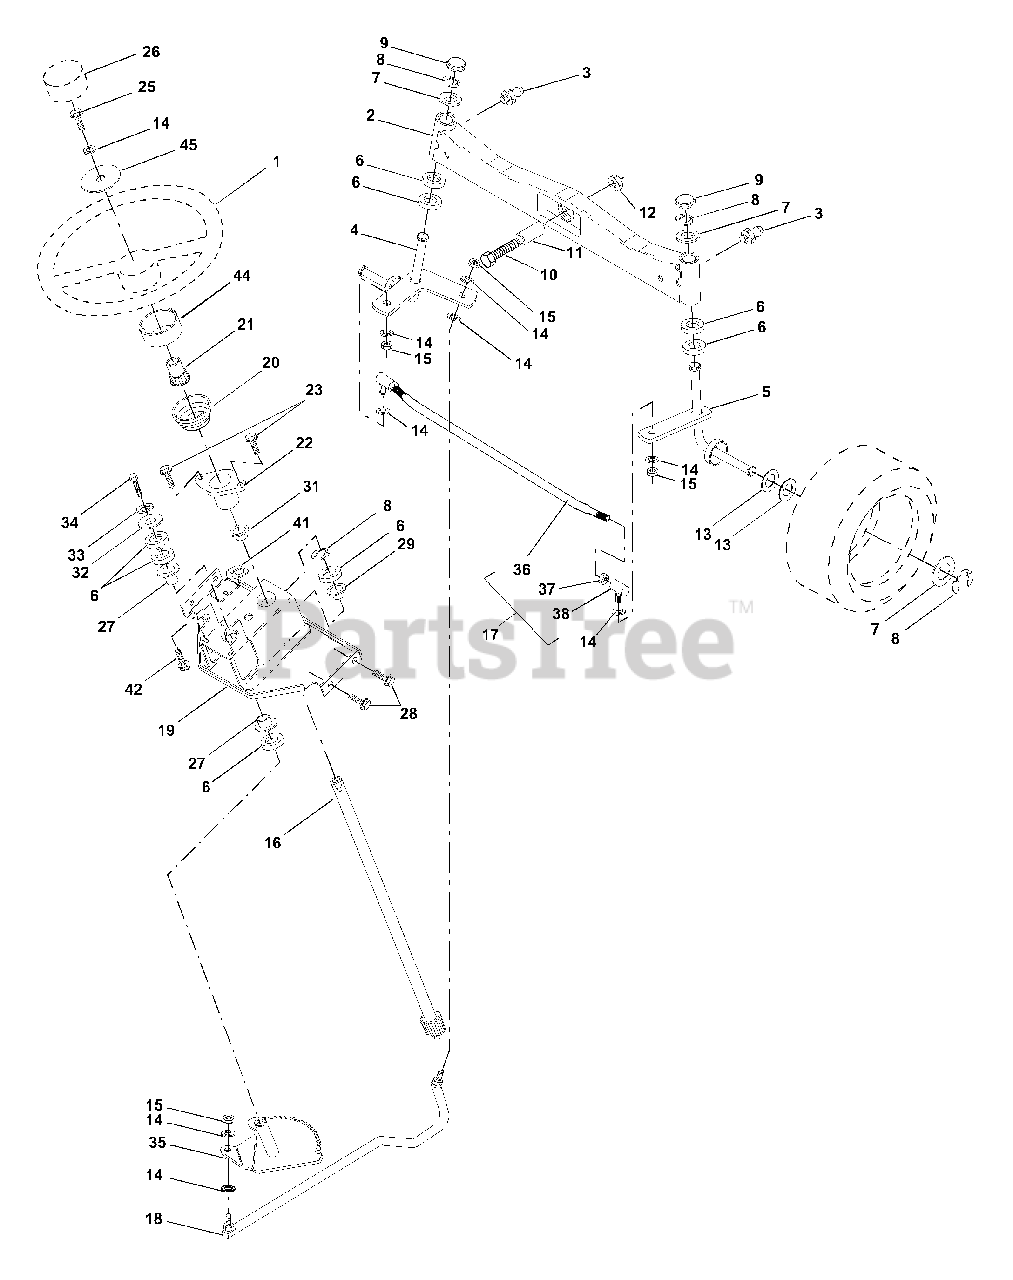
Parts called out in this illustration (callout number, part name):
1	Wheel, Steering
2	Axle Asm., Front
3	Fitting, Grease
4	Spindle Asm, LH
5	Spindle Asm., RH
6	Bearing, Race Thrust Harden
7	Washer 25/32 x 1-5/8 x 16 Ga.
8	Ring, Klip #T5304-75
9	Cap, Spindle
10	Bolt, Fin Hex 5/8-11 x 2-3/4
11	Spacer Brg Axle Front 1.570
12	Nut, Lock Flange 5/8-11 Unc
13	Washer 25/32 x 1-1/4 x 16 Ga.
14	Washer, Lock Hvy Hlcl Spr 3/8
15	Nut Lock Center 3/8-24 Unf
16	Shaft Asm., Steering
17	Rod Asm., Tie Ball J Ball Vgt
18	Draglink, Ball Joint Solid Vgt
19	Support Asm., Steering Vgt
20	Boot Steering
21	Adapter, Wheel Steering
22	Bushing, Strg.
25	Bolt, Fin Hex 3/8-16 x 1 Gr. 5
26	Cap , Wheel Steering
27	Bearing, Col. Strg.
28	Screw 3/8-16 x 3/4
29	Bearing, Flange
31	Bushing, Nyliner Snap
32	Washer 11/32 x 1 x 10 Ga.
33	Washer, Lock Hvy Hlcl Spr 5/16
34	Bolt, Hex Hd 5/16-18 x 3/4
35	Gear, Sector Steering
36	Tie Rod
37	Jam Nut RH Thread
38	Joint Asm. Ball RH Thread
41	Bracket Switch Inerlock VGT97
42	Screw 5/16-18 x 1/2
44	Extension Steering Premium
45	Washer 13/32 x 1-1/20 x 11 Ga.
